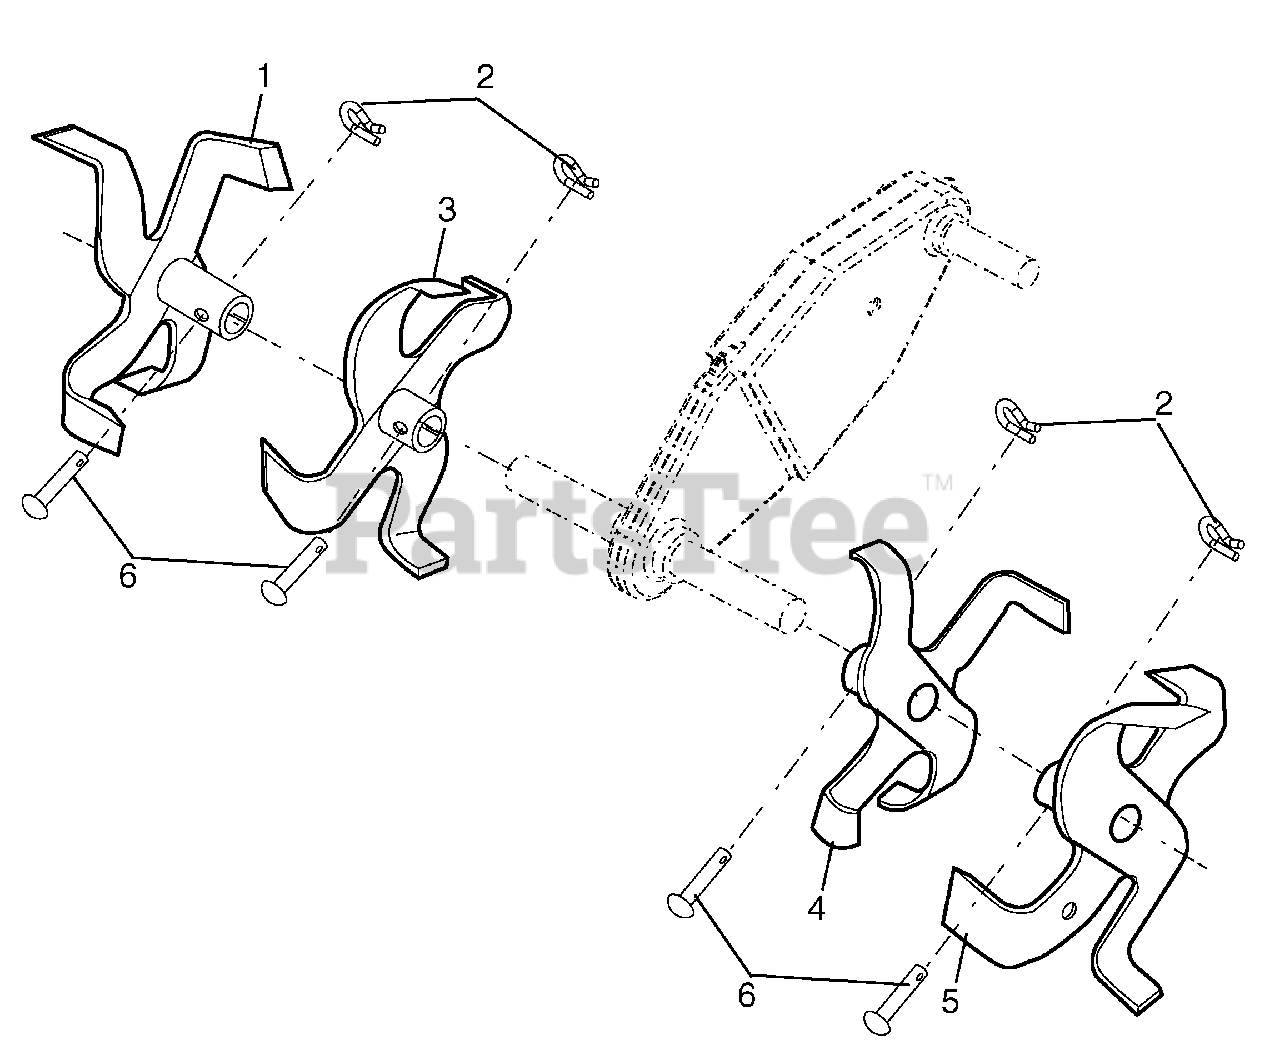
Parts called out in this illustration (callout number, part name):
1	Tine, Outer, R.H.
2	Retainer, Spring
3	Tine, Inner, R.H.
4	Tine, Inner, L.H.
5	Tine, Outer, L.H.
6	Pin, Clevis
